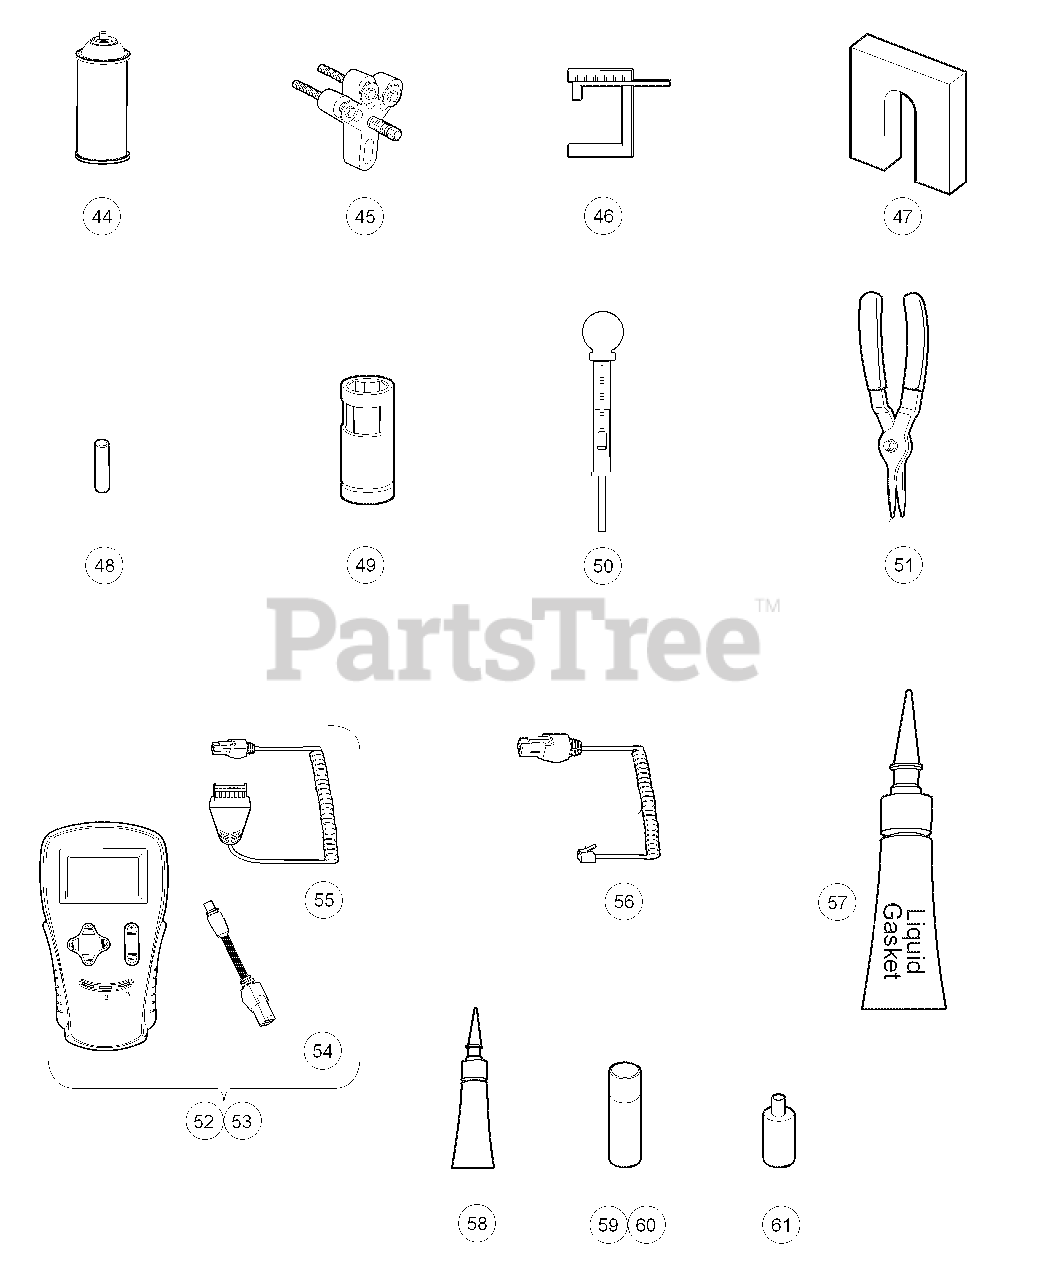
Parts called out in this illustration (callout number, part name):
44	Dry Moly Lubricant
45	Flywheel Puller Kit
46	Gauge, Carburetor Float Level
48	Governor Shaft Installation Tool
49	Hydraulic Brake Adjuster
50	Hydrometer
51	Internal Retaining Ring Pliers
52	IQ Display Module Kit
53	IQ Display Module Kit
54	Adaptor, Cable
55	IQDM Series 2 Cable
56	IQDM Series 1 Cable
57	Liquid Gasket
58	Moly-Teflon Lubricant
59	Paint, Touch-Up – Beige
59	Paint, Touch-Up – Black
59	Paint, Touch-Up – Burgundy
59	Paint, Touch-Up – Classic Blue
59	Paint, Touch-Up – Dark Gray
59	Paint, Touch-Up – Dark Green
59	Paint, Touch-Up – Gray
59	Paint, Touch-Up – Red
59	Paint, Touch-Up – Royal Blue
59	Paint, Touch-Up – White
60	Paint, Precedent Underbody – Gray
61	Paint Pen, Touch-Up, Precedent Underbody – Black
